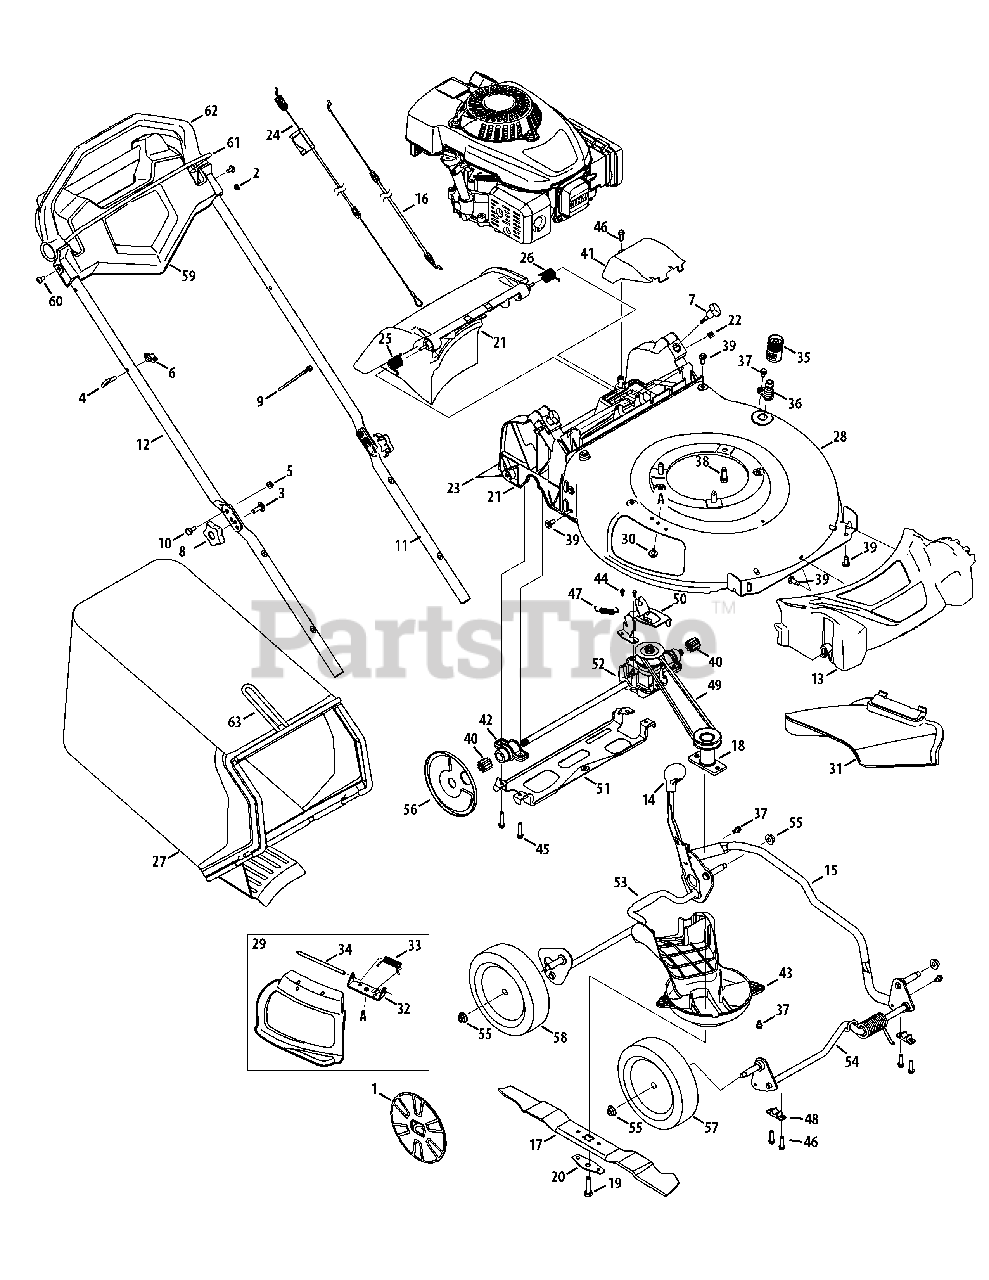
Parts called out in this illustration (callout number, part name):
1	Hubcap
2	Spacer
3	Carriage Screw ,5/16-18
4	Rope Guide
5	Nut, Flange Lock, 1/4-20
7	Wing Nut
8	Star Knob
9	Cable Tie
10	Shdr. Screw, .375 x .126 x 1/4-20
11	Lower Handle
12	Upper Handle
13	Front Cover
14	Adjustment Knob
15	Tube, Link
16	Control Cable
17	Mulching Blade
18	Blade Adapter
19	Screw, 3/8-24 x 1.50
20	Blade Bell Support
21	Rear Discharge Door Assembly
22	Nut, Sq., 1/4-20
23	Trail Shield
24	Drive Cable
25	Torsion Spring - RH
26	Torsion Spring - LH
27	Grass Bag
28	21" Deck
29	Mulch Plug (Incl. 32-34)
31	Side Discharge Chute
32	Chute Deflector Bracket
33	Torsion Spring
34	Hinge Pin
35	Water Nozzle Adapter
36	Water Nozzle
37	Scr., Shldr., 1/4-20 x .50
38	Screw, tt, 3/8-16 x 1.00
39	Screw, 5/16-14 x .750
40	Spur Gear, 10T
41	Transmission Cover
42	Bearing Assembly
43	Engine Baffle
44	Screw, Hex Washer, .159 x .43
45	Screw, 1/4-15 x 1.25
46	Screw, 1/4-15 x .750
47	Exten. Spring, 2.675
48	Bush., Block
49	V-Belt
50	Transmission Bracket
51	Rear Support Bracket
52	Transmission
53	Rear Hgt. Adjust./Axle Assembly
54	Front Axle Assembly
55	Flange Lock Nut, 3/8-16
56	Wheel Dust Cover
57	Front Wheel, 8 x2
58	Rear Wheel, 8 x 2
59	Handle Console
60	Screw, 1/4-14 x .625
61	Blade Control
62	Premium Drive Control
63	Grass Catcher Frame
